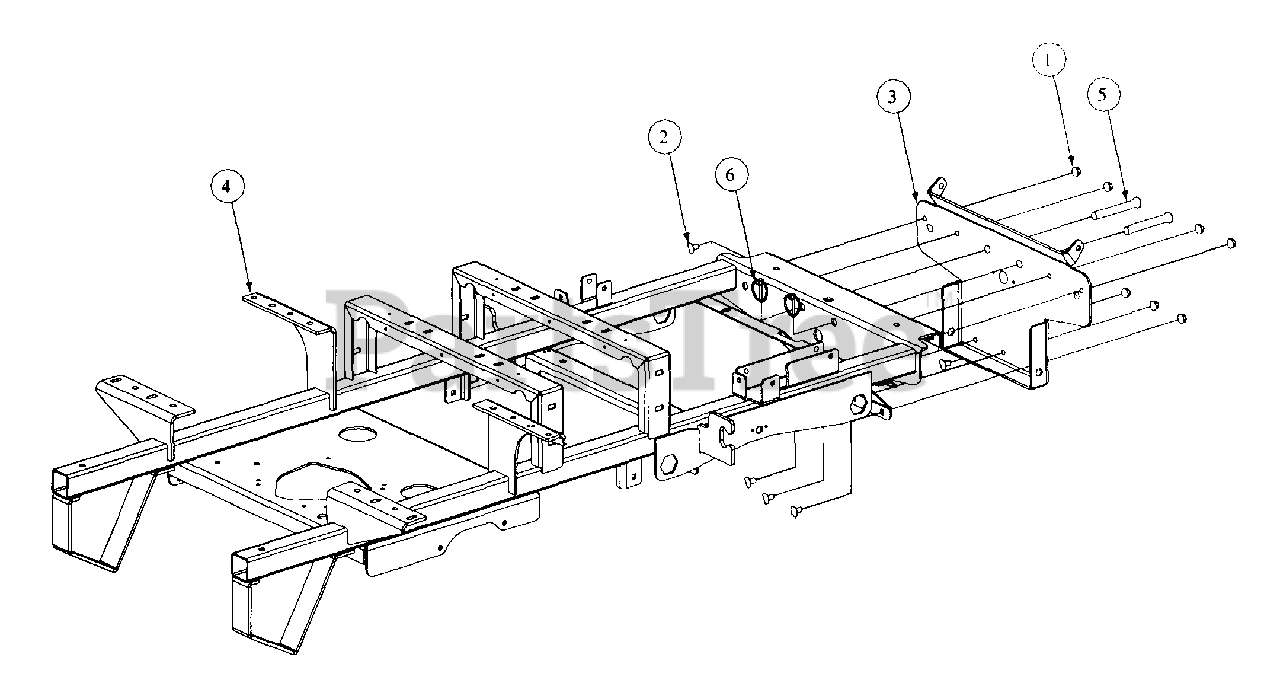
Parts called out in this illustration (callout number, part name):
1	Hex Nut, 3/8-16 Flange Lock
2	Carriage Bolt, 3/8-16 x .75 Long
3	Bracket Assembly, Frame, Front
4	Frame Assembly
5	Clevis Pin, .500 Dia x 4.375 Long
6	Linch Pin, 3/16 Dia.
